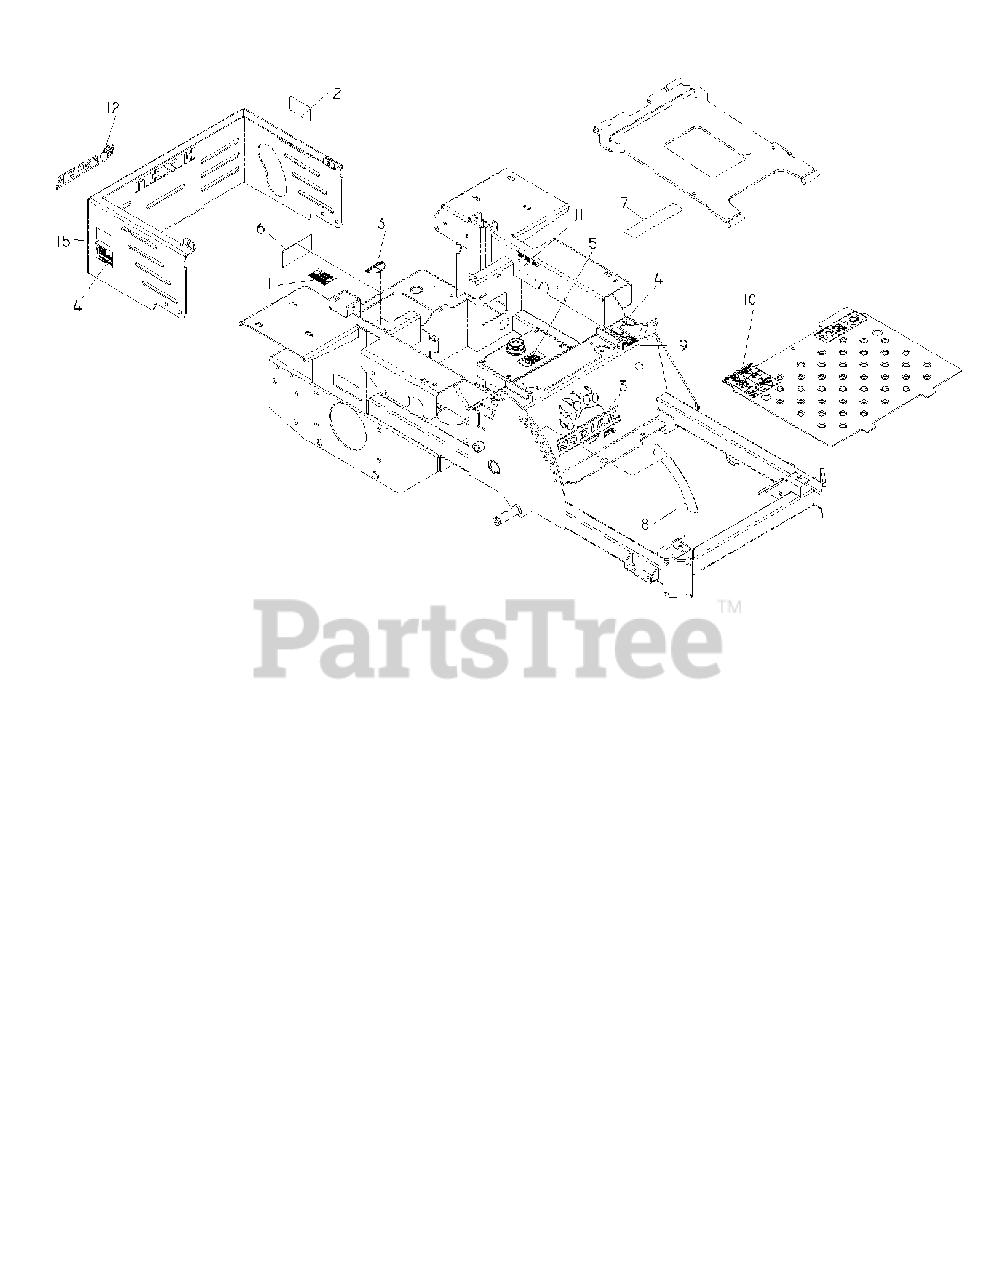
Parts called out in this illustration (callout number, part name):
1	DECAL, EXHAUST
2	DECAL, PROP. 65
3	DECAL, FUEL VALVE
4	DECAL, MOTION CONTROL
5	DECAL, OIL TANK
6	DECAL, BELT DRIVE
7	DECAL, BATTERY
9	DECAL, F.S.T.
10	DECAL, WARNING
11	DECAL, RELAYS
12	DECAL, PRO ZTR
13	DECAL, KODIAK
14	DECAL, PARKER
15	DECAL, KOHLER
